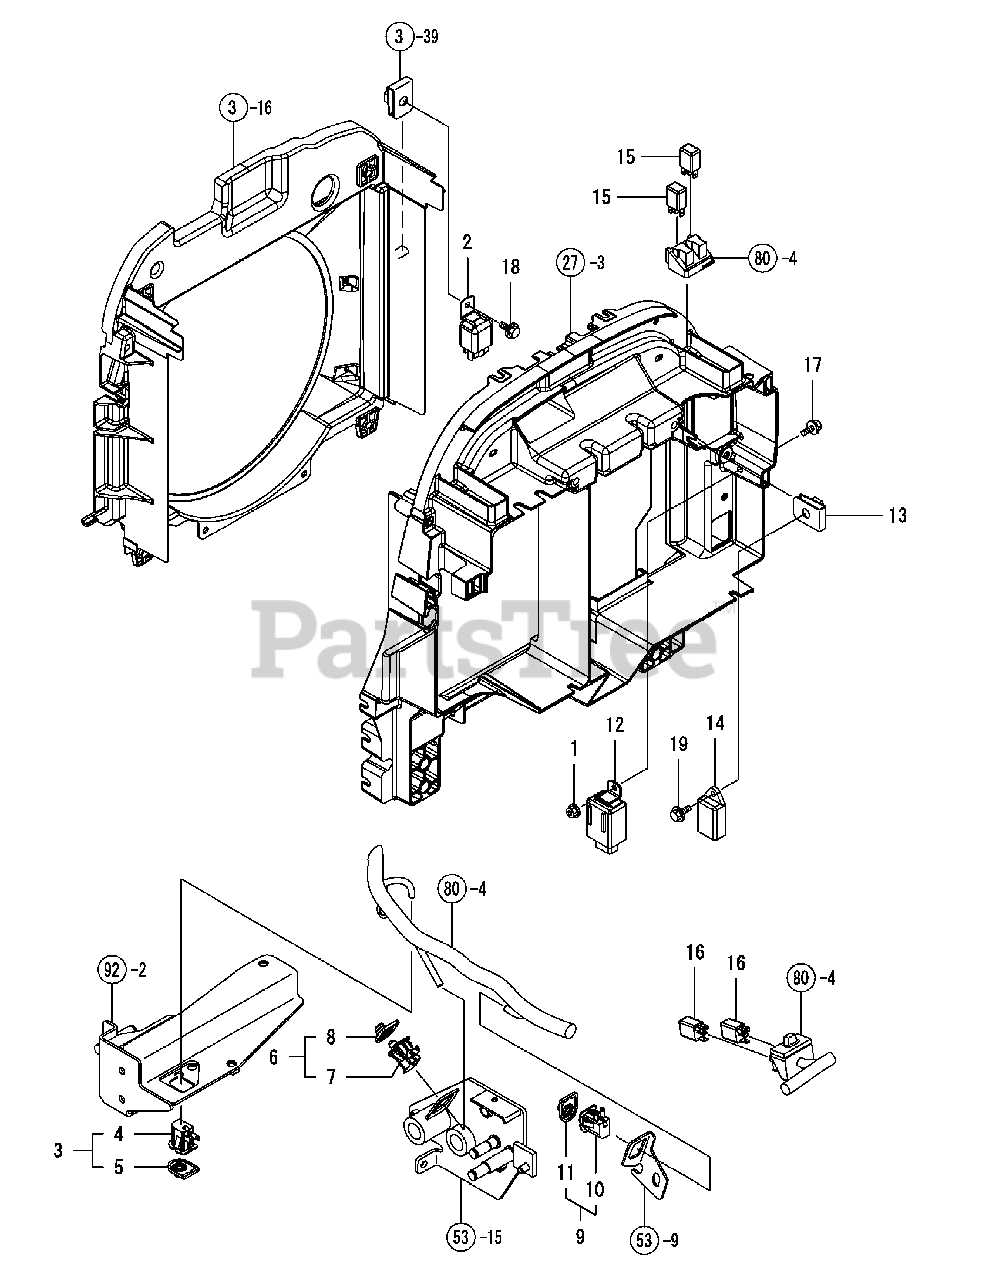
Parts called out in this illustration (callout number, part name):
1	NUT W/WASHER 6
2	RELAY, STARTER
3	SWITCH NC ASSY, PEDAL
3-1	SWITCH-BRAKE PEDAL SC
3A	NUT-HEX LOCK M12 PLTD
4	SWITCH NC, PEDAL
5	PROTECTIVE COVER,
6	SWITCH NC ASSY, PEDAL
7	SWITCH NC, PEDAL
8	PROTECTIVE COVER
9	SWITCH, SEAT, DELTA, AS
10	SWITCH, SEAT, DELTA, AS
11	PROTECTIVE COVER
14	TIMER, FUEL SOLENOID 1 SEC
15	RELAY, STARTER (ACM13211M01)
16	RELAY, STARTER (ACM13211M01)
17	BOLT M 6X 16 PLATED
18	BOLT M 6X 16 PLATED
19	BOLT M 6X 16 PLATED
